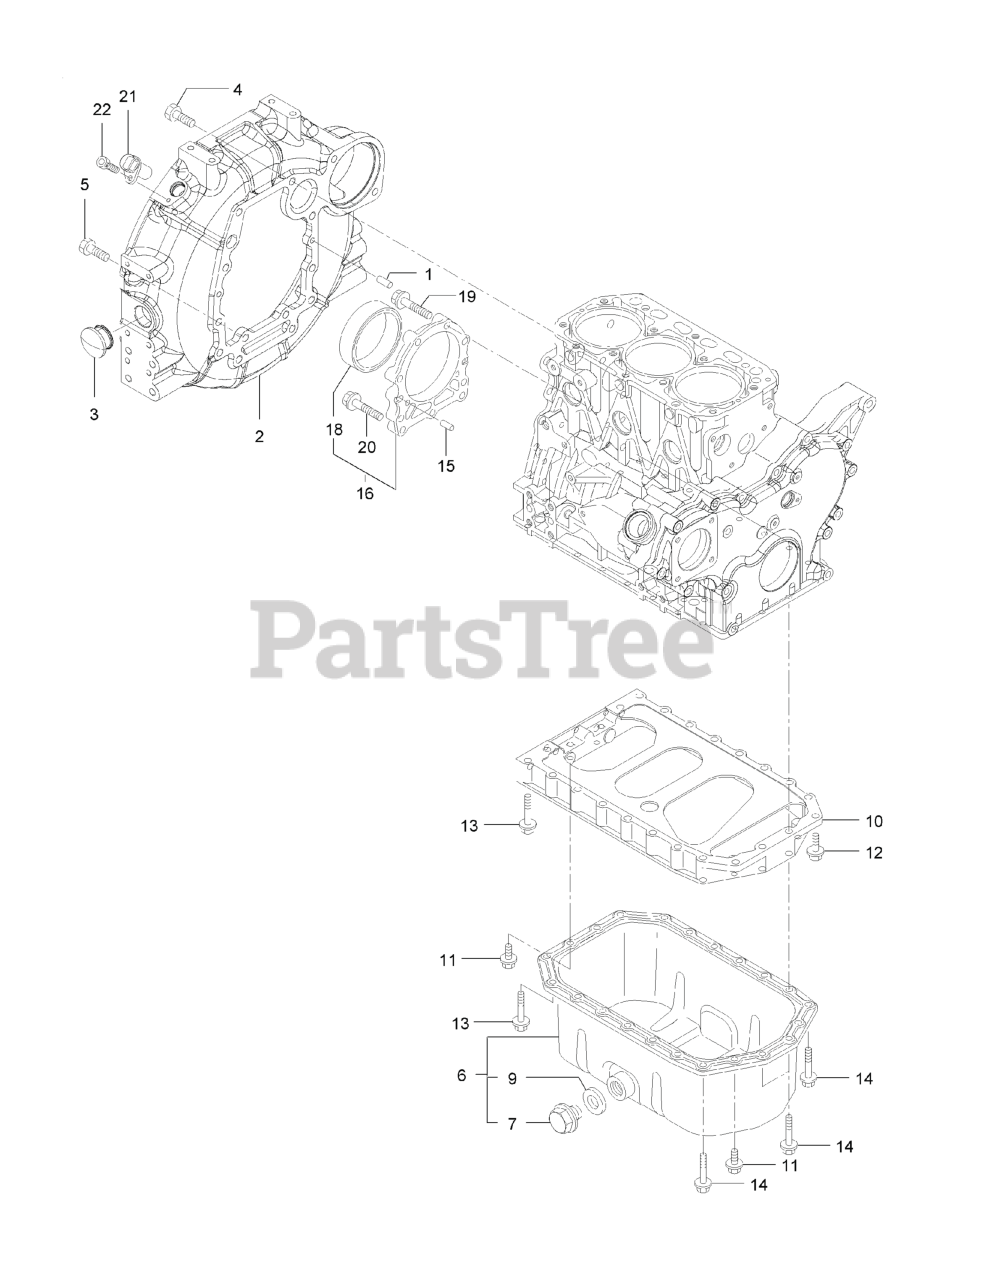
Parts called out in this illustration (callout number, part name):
2	HOUSING-FLYWHEEL
6	OIL PAN ASM
7	PLUG-DRAIN
9	WASHER-SEAL
11	BOLT
16	CASE ASM
18	SEAL-OIL
21	SENSOR-REV, FLYWHEEL
